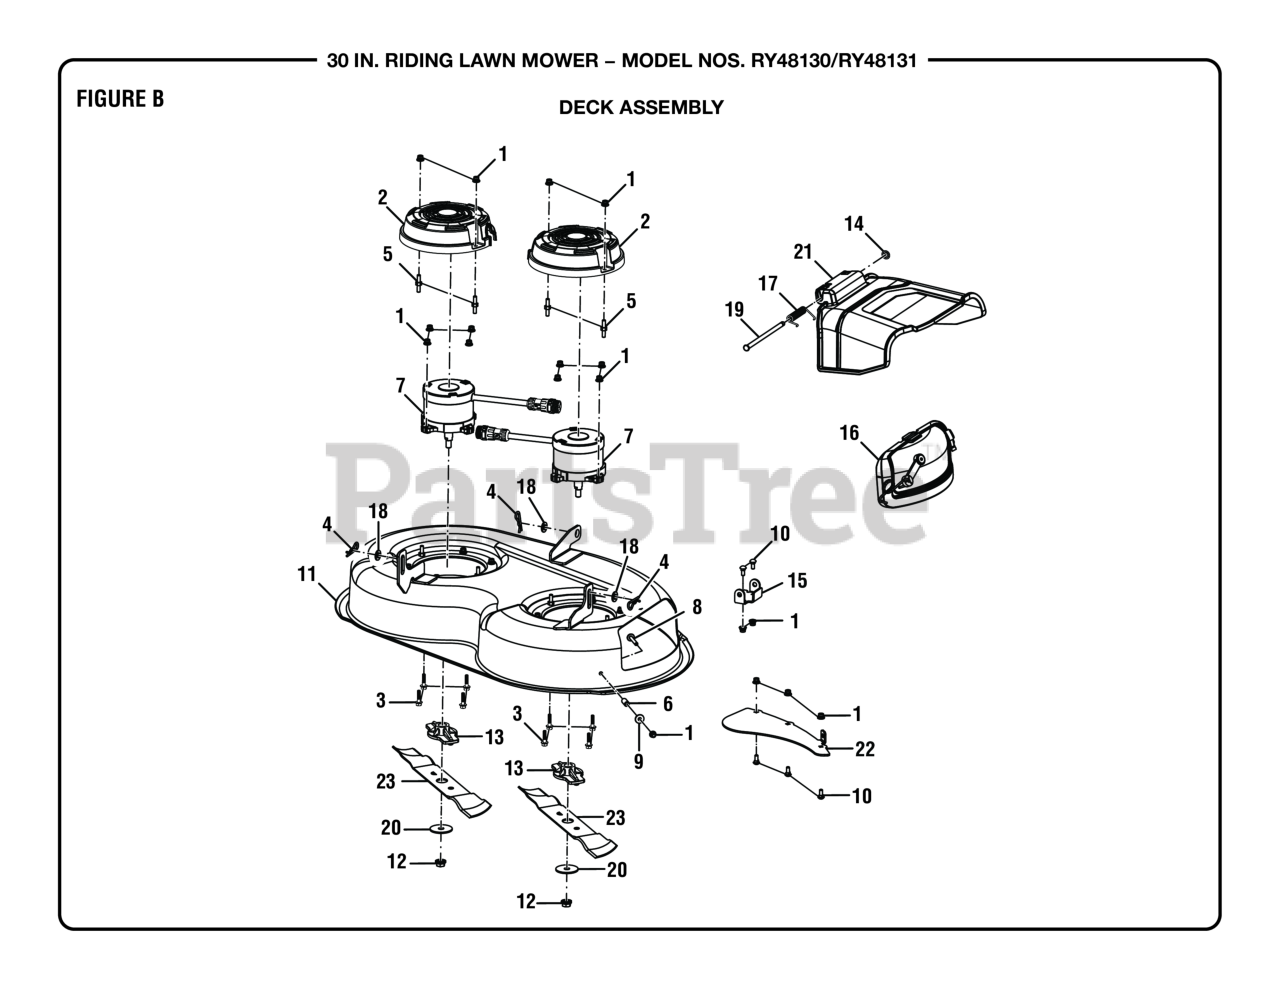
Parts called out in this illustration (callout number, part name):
1	Flange Lock Nut (M6 x 1.00)
2	Deck Motor Cover
3	Flange Bolt (M6 x 25 mm, Hex Hd.)
4	Cotter Pin
5	Deck Motor Stud
6	Deck Bagger Chute Mounting Shaft
7	Deck Motor
8	Screw (M6 x 40, Soc Hd.)
9	Washer (OD18 x ID6.4 x 1.6t)
10	Carriage Bolt (M6 x 16 mm)
12	Flange Lock Nut (M10 x 1.25)
13	Blade Adapter
14	Retainer Clip
15	Discharge Door Bracket
16	Mulch Plug
17	Discharge Spring
18	Washer (OD20 x ID10.5 x 2t)
19	Hinge Pin (7.85 x 175.85)
20	Blade Retainer Washer
21	Discharge Chute
23	Blade (15 in.)
